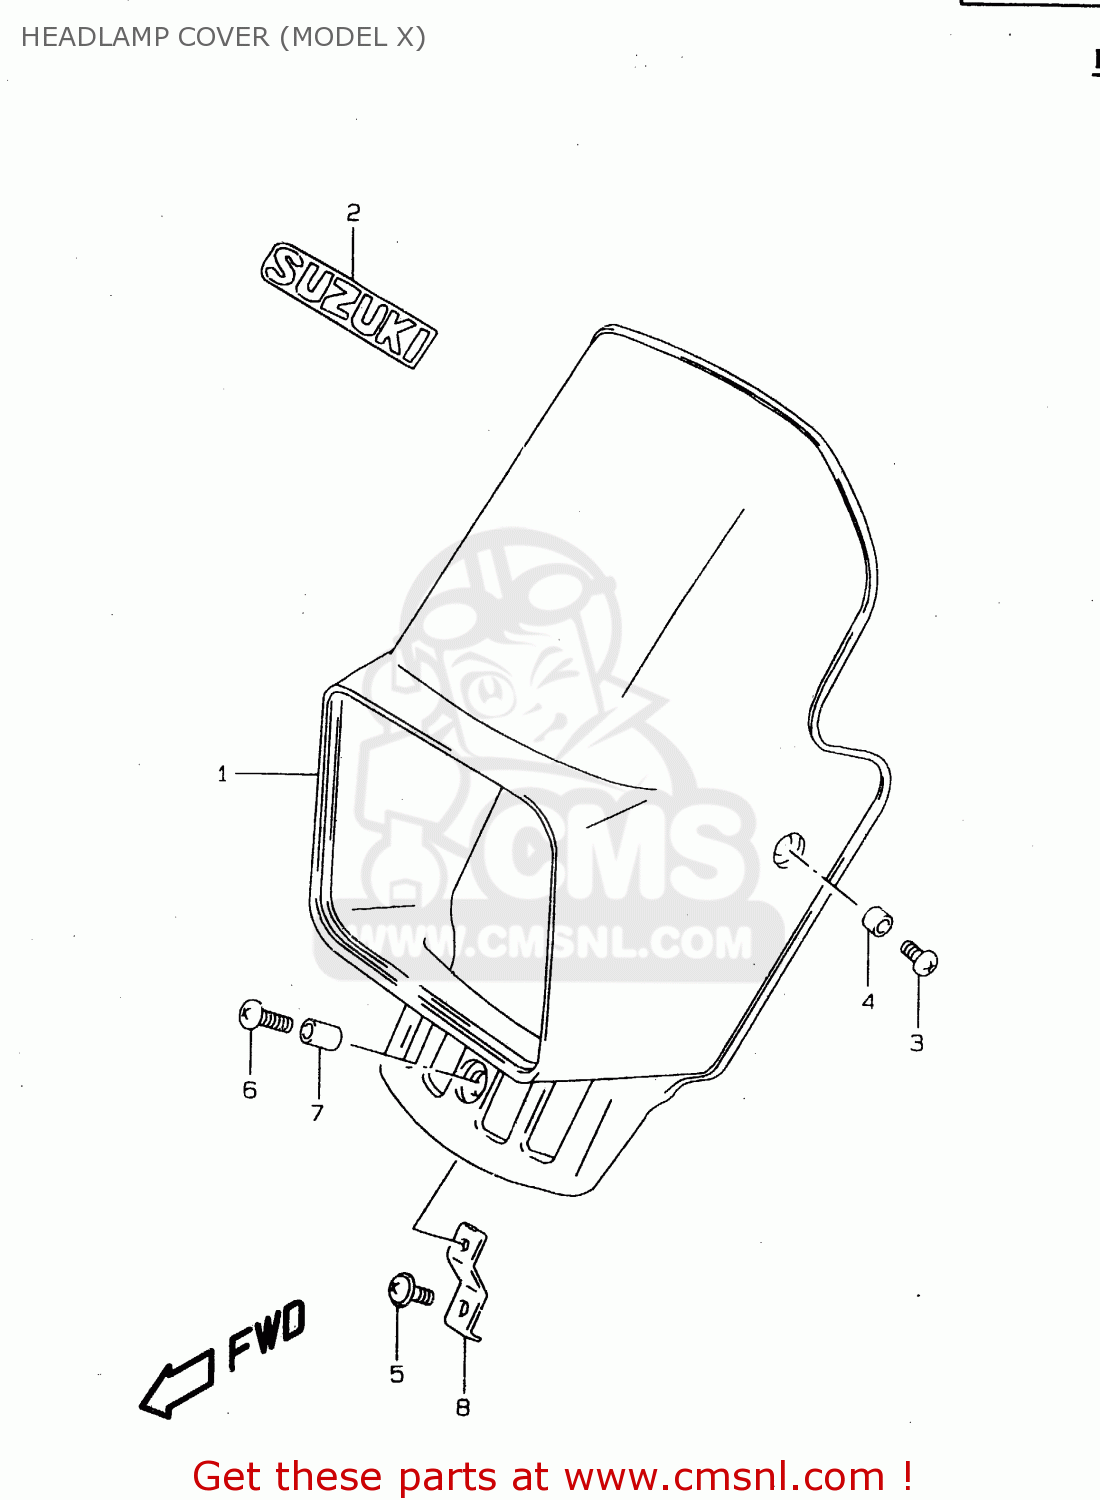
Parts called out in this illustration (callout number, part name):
1	COVER,HEADLAMP
2	EMBLEM
3	SCREW 6X12
4	SPACER(6.1X8X3.5)
5	SCREW
6	SCREW
7	SPACER(6.1X8X12)
8	BRACE,HEADLAMP HOUSING LWR
